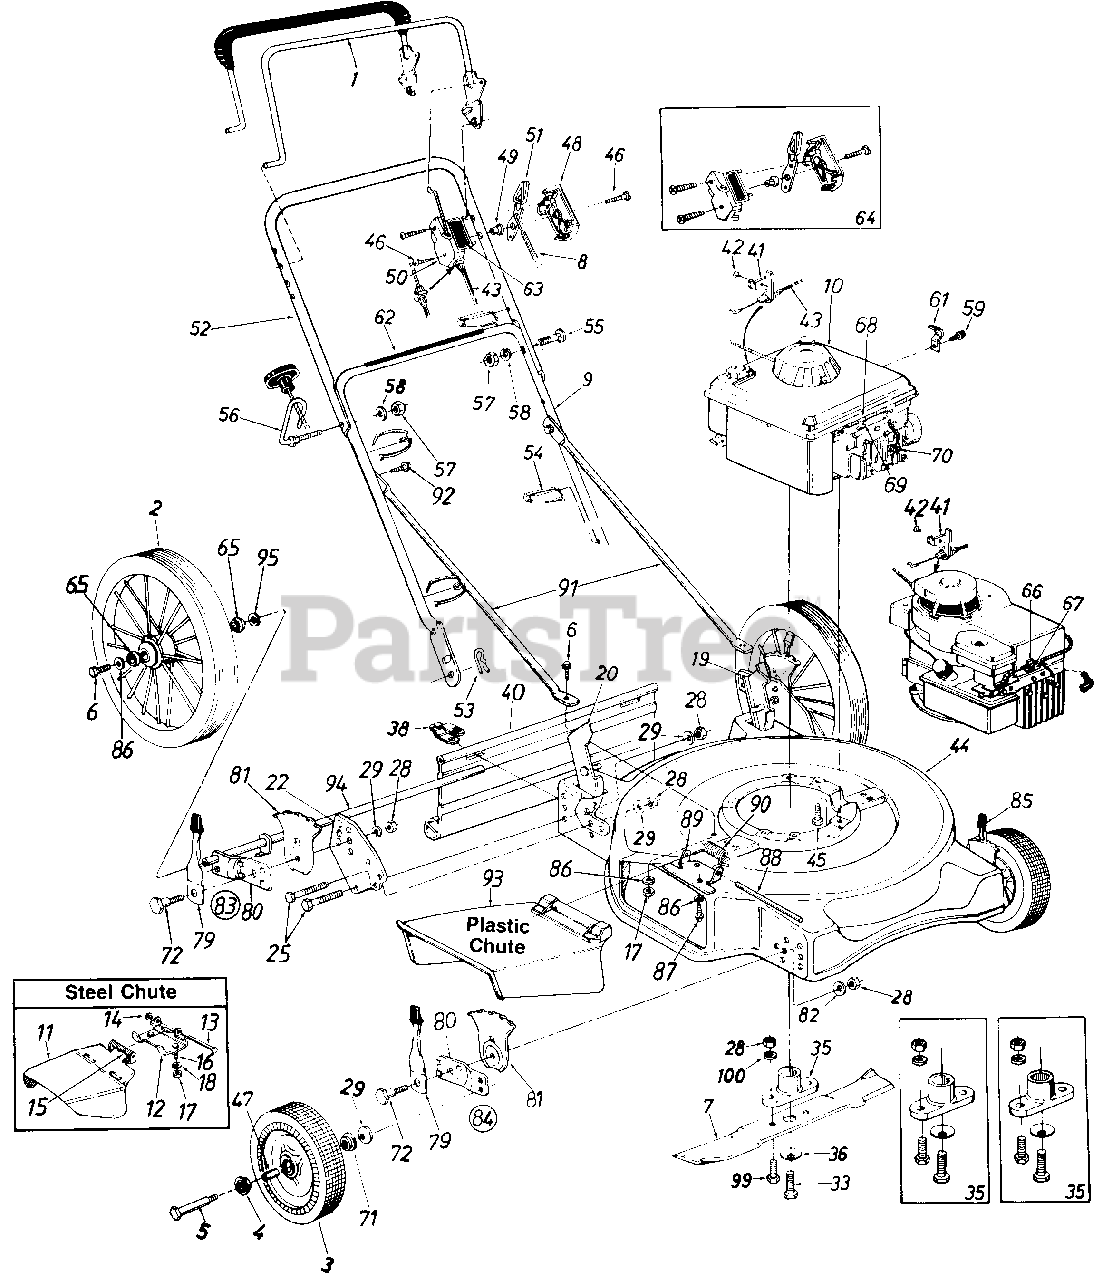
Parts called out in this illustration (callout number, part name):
1	Control Handle
2	14" Wheel Ass'y.-Comp.
3	Front Wheel Ass'y.-Comp. 8" x 1.75"
4	Bearing 1/2" I.D.
5	Front Axle Bolt
6	Hex Bolt 1/4-20 x .62" Lg.*
7	22" Blade
8	Throttle Wire-53"
9	Lower Handle (Painted)
10	Engine
11	Chute Deflector Ass y. Comp.
12	Adapter Plate
13	Pivot Pin
14	Push Nut 1/4" Rod
15	Torsion Spring
16	Hex Bolt 1/4-20 x .50" Lg.*
17	Hex Nut 1/4-20 Thd.*
18	L-Wash. 1/4" I.D.*
19	Handle Mount Brkt.-L.H.
20	Handle Mount Brkt.-R.H.
22	Mounting Plate
25	Hex Bolt 3/8-16 x .75" Lg.
28	Hex Nut 3/8-16 Thd.*
29	Bell-Wash. .400" I.D. x .88"
33	Hex Bolt 7/16-20 x 1.5" Lg.
35	Blade Adapter Kit (Splined)
36	Bell-Wash. .46" I.D. x 1.12"
38	Hinge Clip
40	Rear Flap Ass'y.
41	Cable Bracket
42	Pop Rivet
43	Control Cable-39"
44	22" Deck Ass'y.
45	Hex Wash. Hd. TT-Tap Scr. 3/8-16 x 1.00" Lg.
46	Truss Mach. "B"-Tap Scr. #12 x 1.50" Lg.
47	Spacer
48	Control Panel Half
49	Control Disc Pin
50	Clutch Panel Half
51	Throttle Control Lever
52	Upper Handle (Painted)
53	Intern. Cot. Pin 5/16" Dia.
54	Cable Tie
55	Curved Carriage Bolt 5/16-18 x 1.38" Lg.
56	Rope Guide Bolt
57	Hex Nut 5/16-18 Thd.
58	L-Wash. 5/16" I.D.
59	Hex B-Tap Scr. #10 x .38" Lg.
61	Cable Clamp
62	Instruction Label-Handle
63	Control Label-Throttle
64	Control Housing Comp.
65	Flange Bearing
66	Cable Clamp
67	Hex AB-Tap Scr. #8 x .38" Lg.
68	Casing Clamp
69	Hex B-Tap Scr. #10 x .62"
70	Spark Plug Boot
71	Ball Bearing 3/8" I.D.
72	Shoulder Bolt .50" Dia.
79	Spring Lever Ass'y. w/Knob
80	Order Rear Height Adj. Ass'y. Comp.
81	Height Adj. Plate
82	Bell-Wash. .39" I.D. x 1.38"
83	Rear Height Adj. Ass'y. Comp.-R.H.
84	Front Height Adj. Ass'y. Comp.-R.H.
85	Front Height Adj. Ass'y. Comp.-L.H.
86	Bell-Wash. .265" I.D. x .75" O.D.
87	Hex Wash. Hd. Tap Scr. 1/4-20 x .5" Lg.
88	Hinge Pin
89	Adapter Plate
90	Torsion Spring
91	Strut 22.95" Lg.
92	Hex Wash. AB-Tap Scr. 5/16 x .75" Lg.
93	Chute Deflector Ass'y. Comp.
94	Rear Axle Ass'y.
95	Fl-Wash.
99	Hex Bolt 3/8-16 x 1" Lg.
100	L-Wash. 3/8 I.D.
